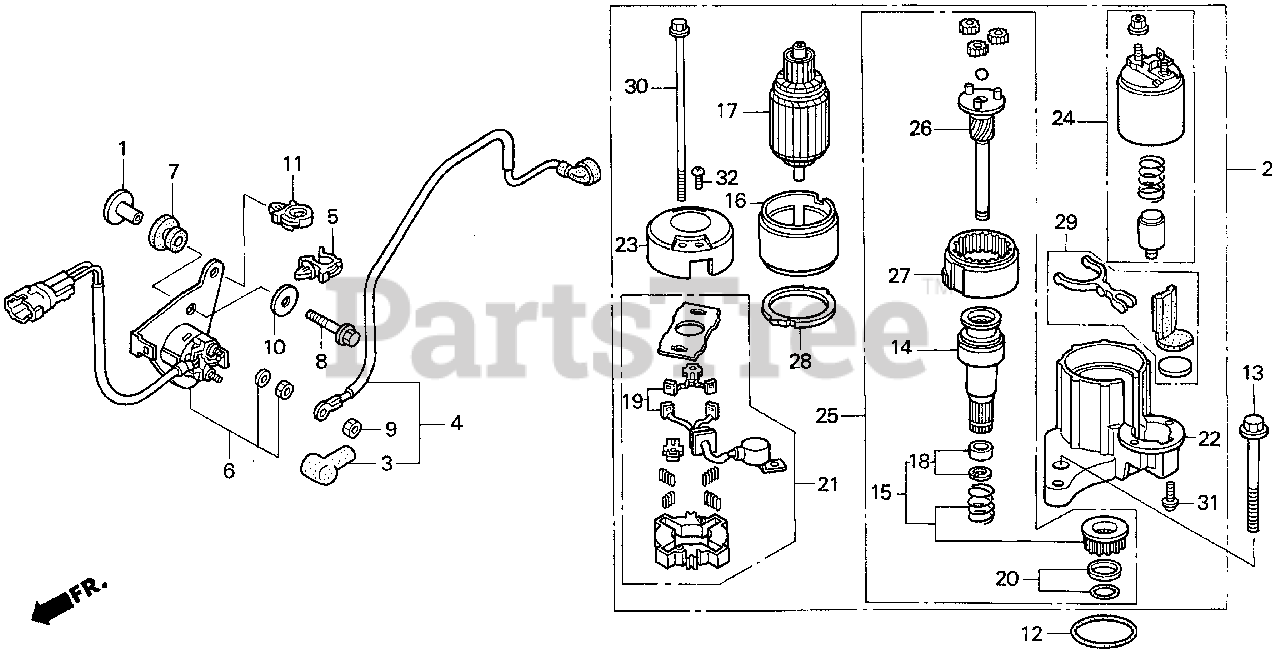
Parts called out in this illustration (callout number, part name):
1	COLLAR, FUEL TANK MOUNTING
2	MOTOR ASSY., STARTER
3	COVER, TERMINAL
4	WIRE, MAGNETIC SWITCH
5	CLAMP, WIRE
6	SWITCH ASSY., STARTER MAGNETIC
7	RUBBER A, LICENSE BRACKET CUSHION
8	BOLT, FLANGE (6X25)
9	NUT, HEX. (6MM)
10	WASHER, PLAIN (6MM)
11	CLIP, WIRE HARNESS
12	O-RING (54.4X3.1)
13	BOLT, FLANGE (10X90)
14	CLUTCH, OVERRUNNING
15	GEAR SET, PINION
18	STOPPER SET, PINION
20	STOPPER SET, SLEEVE
21	HOLDER, BRUSH
22	BRACKET, FR.
23	BRACKET, RR.
24	SWITCH ASSY., MAGNET
25	SHAFT ASSY., CLUTCH
26	SHAFT ASSY., GEAR
27	GEAR ASSY. (INNER)
30	BOLT A, THROUGH
31	SCREW, PAN (6X22) (SPECIAL)
32	SCREW, PAN (5X8)
